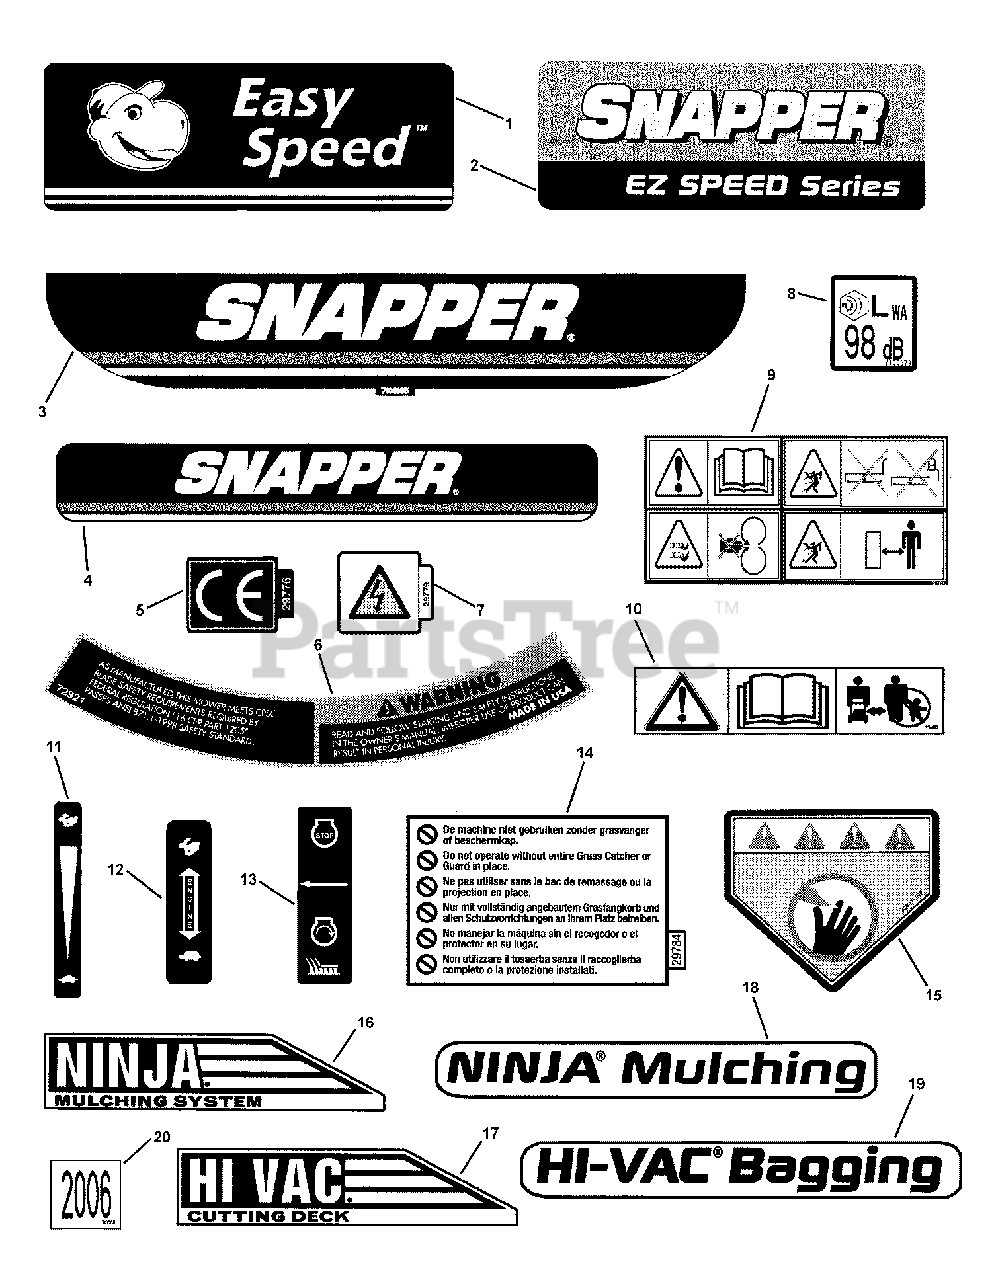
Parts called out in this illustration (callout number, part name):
1	DECAL, Easy Speed, Control Panel
2	DECAL, Easy Speed, Control Panel
3	DECAL, Snapper, Steel Decks
4	DECAL, Snapper, Front Cover
5	DECAL, Euro Community (CE)
6	DECAL, Warning (Deck)
7	DECAL, Spart Plug International Symbol
8	DECAL, Noise, 98 dB
9	DECAL, Warning, Euro, Multi-Panel
10	DECAL, Caution, Symbols
11	DECAL, Speed Shift
12	DECAL, Throttle Control, B&S
13	DECAL, OPC Bail (International Symbol)
14	DECAL, Deck/Chute International Warning
15	DECAL, Warning (Euro)
16	DECAL, Ninja, Mulching System
17	DECAL, Hi Vac, Cutting Deck
18	DECAL, Front Cover, Ninja Mulching System
19	DECAL, Front Cover, Hi-Vac
20	DECAL, 2006 Year of Mfg.
